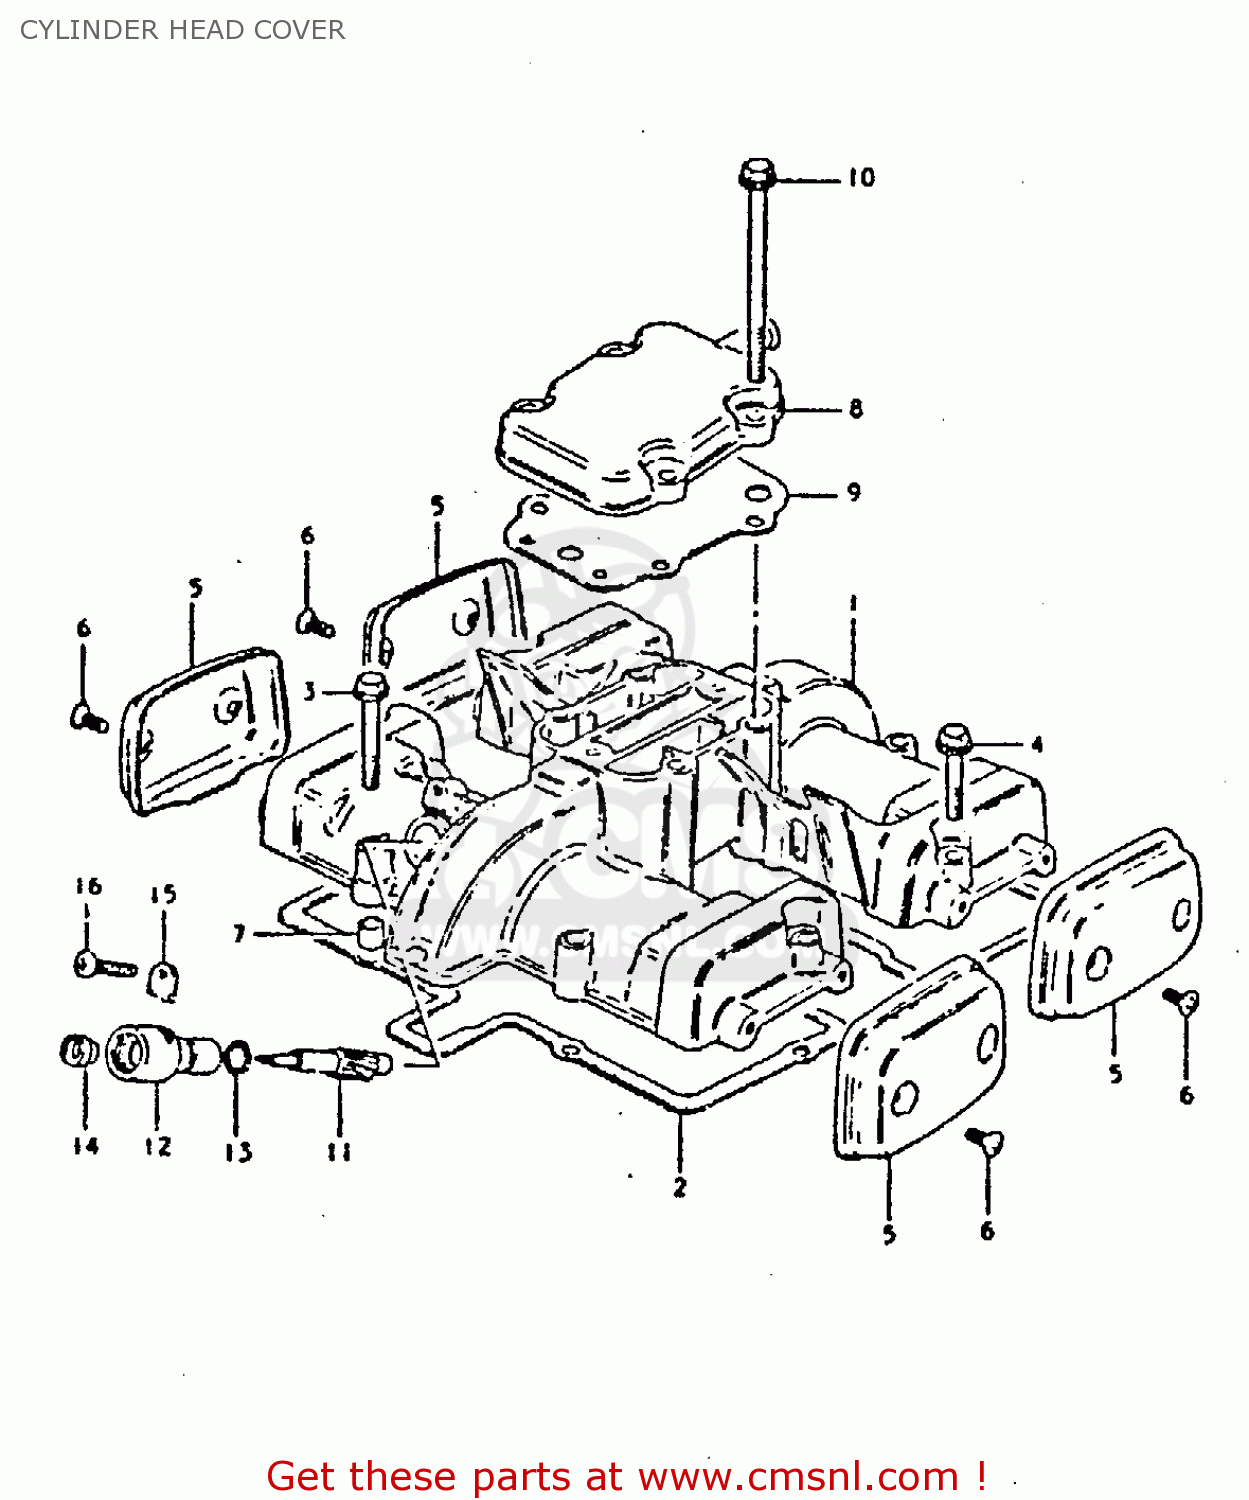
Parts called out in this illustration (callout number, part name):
1	COVER,CYLINDER HEAD
2	GASKET,CYLINDER HEAD COVER (MCA)
3	BOLT
4	BOLT 6X35
5	UNION,CYLINDER HEAD OIL
6	SCREW 5X12
7	PIN(6.2X8X11)
8	COVER,BREATHER
9	GASKET,BREATHER COVER (MCA)
10	BOLT (6X75)
11	GEAR,TACHOMETER DRIVEN
12	SLEEVE
13	SEAL,TACHOMETER DRIVEN
14	SEAL,OIL(5X12X8)
15	PLATE,TACH DRIVE GEAR SLEEVE
16	SCREW(5X12)
